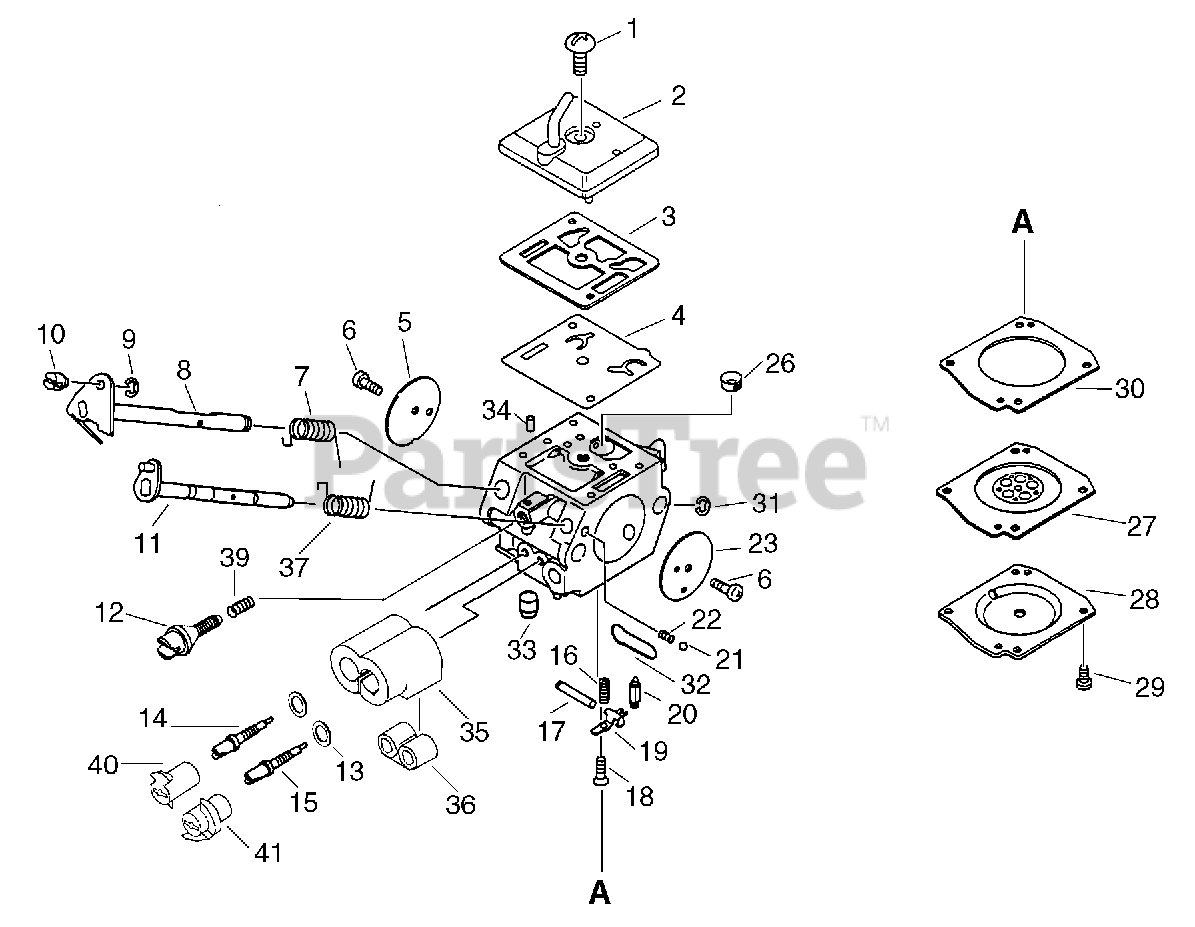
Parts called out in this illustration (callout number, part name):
2	COVER, PUMP
3	GASKET, PUMP
4	DIAPHRAGM, PUMP
5	VALVE, THROTTLE
6	SCREW 3×4.5
7	SPRING, THROTTLE RETURN
8	SHAFT ASSY, THROTTLE
10	SWIVEL
11	SHAFT, CHOKE
12	SCREW, THROTTLE ADJUST
14	SCREW, IDLE ADJUST
15	SCREW, MAIN ADJUST
16	SPRING, COIL
17	PIN, METERING LEVER
19	LEVER, METERING
20	VALVE, INLET NEEDLE
21	BALL, CHOKE
22	SPRING, THROTTLE FRICTION
23	VALVE, CHOKE
26	STRAINER
27	DIAPHRAGM
28	COVER, DIAPHRAGM
30	GASKET, METERING DIAPHRAGM
32	PLUG, WELCH
33	NOZZLE, CHECK VALVE
34	PIECE, FRICTION
35	CAP, LIMITER
36	SCREW, ADJUSTER
37	SPRING, CHOKE RETURN
39	SPRING, IDLE ADJUST
40	CAP, LIMITER
41	CAP, LIMITER
